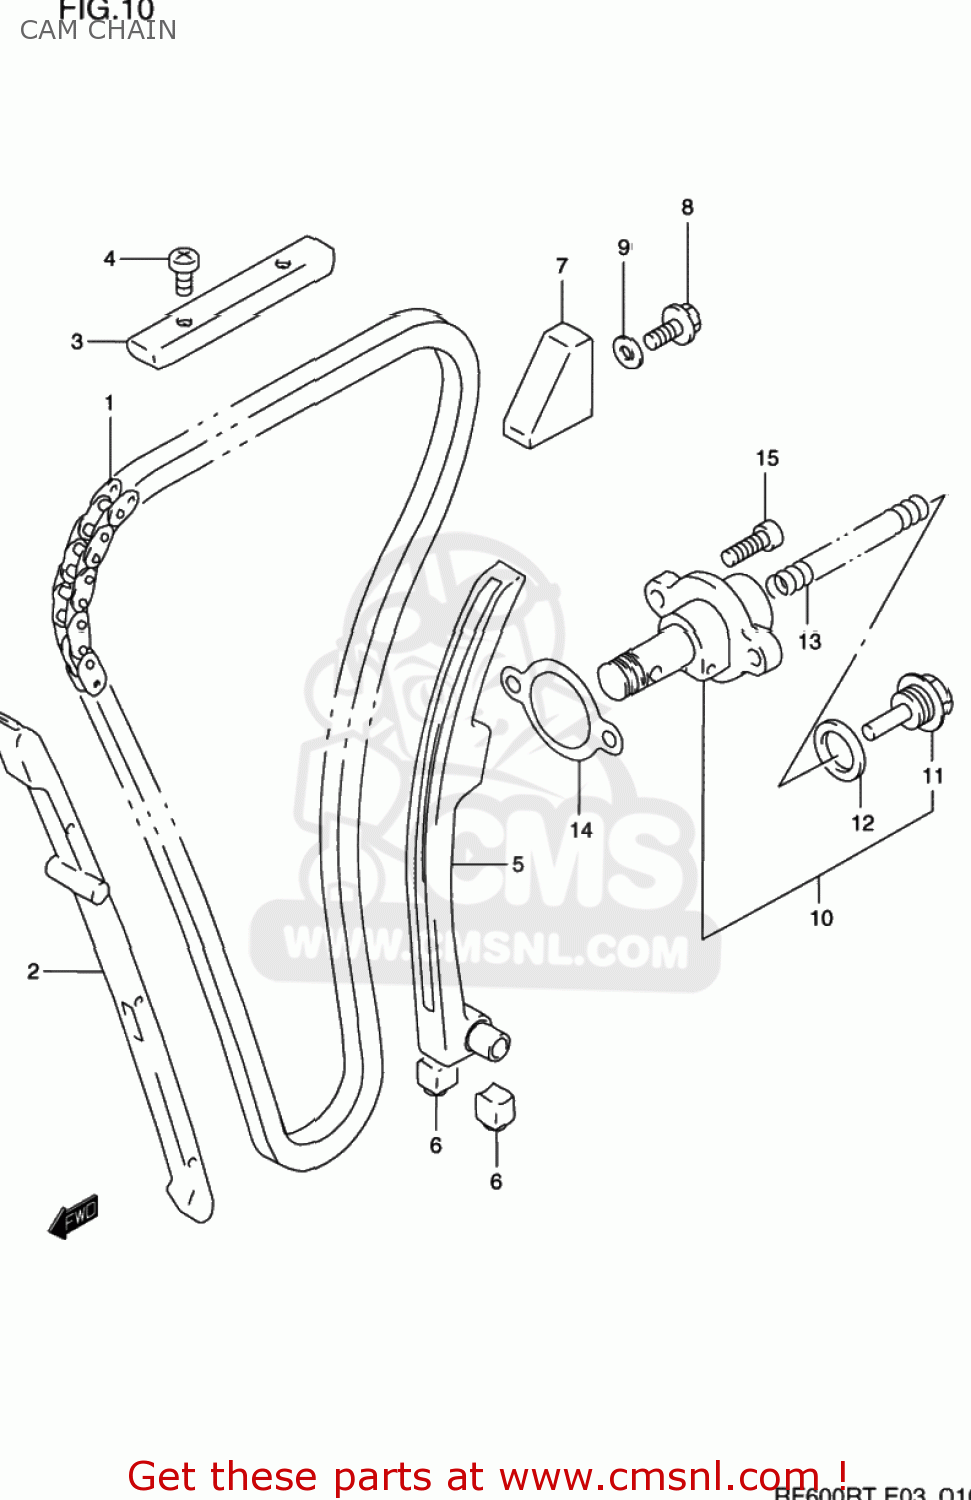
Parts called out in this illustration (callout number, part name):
1	CHAIN,CAMSHAFT DRIVE
2	GUIDE,CAM CHAIN NO.1
3	GUIDE,CAM CHAIN NO.2
4	SCREW
5	TENSIONER,CAM CHAIN
6	CUSHION,CAM CHAIN TENSIONER
7	GUIDE,CAM CHAIN NO.3
8	BOLT
9	GASKET(5.8X13X1.2) (NAS)
10	ADJUSTER ASSEMBLY,TENSIONER
11	PLUG
12	GASKET (NAS)
13	SPRING
14	GASKET,TENSIONER ADJUSTER (NAS)
15	BOLT
